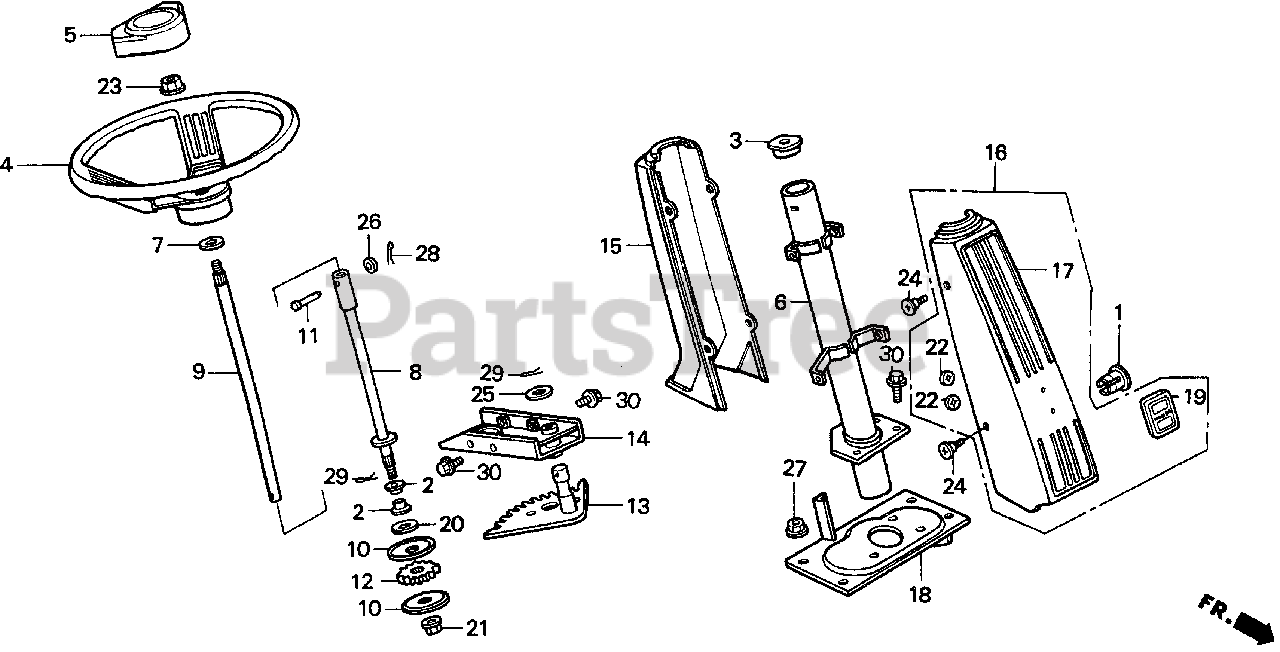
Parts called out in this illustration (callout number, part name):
1	PLUG, CROSS PIPE SETTING *R165* (JOLLY RED)
2	BUSH (17X22X15)
3	BUSH, STEERING SHAFT
4	WHEEL, STEERING
5	PAD, CENTER
6	PIPE, STEERING COLUMN
7	WASHER, STEERING COLUMN
8	SHAFT, STEERING
9	SHAFT, STEERING WHEEL
10	WASHER (14.2X44)
11	PIN (7X30)
12	GEAR, STEERING DRIVE
13	GEAR, STEERING DRIVEN
14	BASE, STEERING
15	COVER, RR. COLUMN *R165* (JOLLY RED)
16	COVER ASSY., FR. COLUMN *R280* (POWER RED)
17	COVER, FR. COLUMN *R280* (POWER RED)
18	PLATE, P.T.O. CLUTCH BASE
19	EMBLEM, FR.
20	WASHER, PIVOT BOLT (NOT AVAILABLE)
21	NUT, AXLE (10MM)
22	NUT, SPEED (4MM)
23	NUT, SELF-LOCK (OHASHI)
24	SCREW, SPECIAL (6X11)
25	WASHER, THRUST (17MM)
26	WASHER, PLAIN (7MM) (NOT AVAILABLE)
27	NUT, FLANGE (8MM)
28	PIN, COTTER (2.0X15)
29	PIN, SPLIT (3.0X25)
29	PIN, COTTER (3.0X45)
30	BOLT, FLANGE (8X16)
